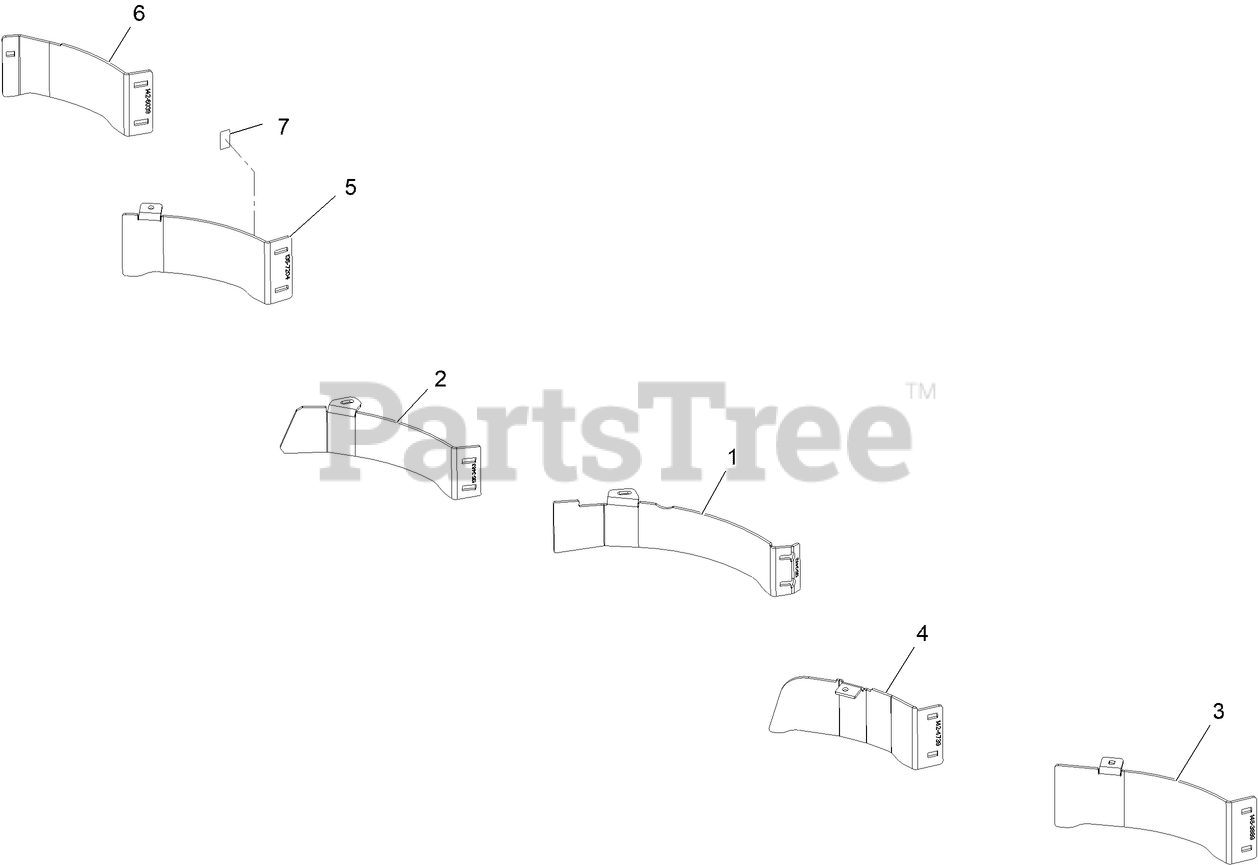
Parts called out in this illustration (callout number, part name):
1	BAFFLE-BLOCK, LH CTR
2	BAFFLE-BLOCK, RH CTR
3	PLATE-BAFFLE, LH MULCH
4	BAFFLE-MULCH, LH INSIDE
5	PLATE-MULCH
6	BAFFLE-WIDE OUTSIDE MULCH
7	DECAL-PATENT
